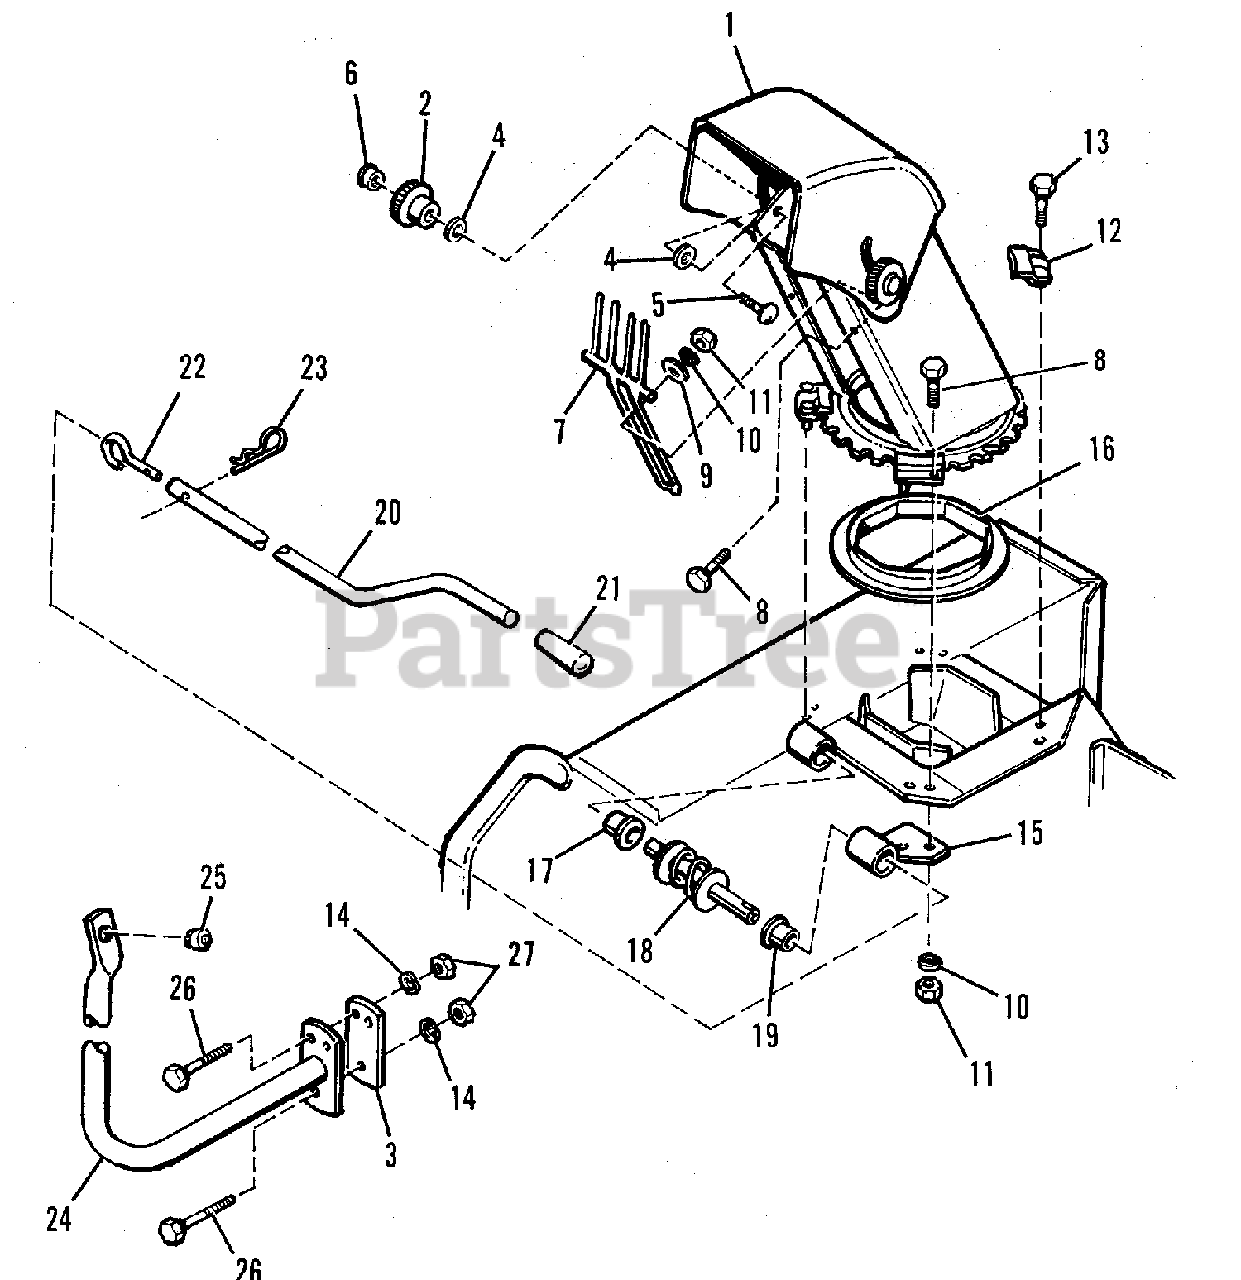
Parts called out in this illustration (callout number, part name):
1	CHUTE & DEFLECTOR ASSEMBLY
3	PLATE, Retaining
4	WASHER, Nylon, 13/32 x 1 x 1/16
5	CARRIAGE BOLT, 5/16-18 x 1-1/2
6	LOCKNUT, Hex, Esna, 5/16-18
8	CAPSCREW, Hex Head, 1/4-20 x 3/4
9	WASHER, Plain, 5/16
10	LOCKWASHER, 1/4
11	NUT, Hex, 1/4-20
12	PLATE, Retaining
13	CAPSCREW, Hex Head, 1/4-20 x 1/2
14	LOCKWASHER, 3/8
15	SUPPORT, Worm
16	RING, Nylon
17	BUSHING, Plastic, 1-5/16
18	WORM, Rotation, Clockwise
19	BUSHING, Plastic, 1-11/16
21	GRIP, Handle
22	HOOK, Handle
23	CLIP, Hairpin
24	BRACKET, Support, Handle
25	GROMMET, Plastic
26	CAPSCREW, Hex Head, 3/8-16 x 1-1/4
27	NUT, Hex, 3/8-16
